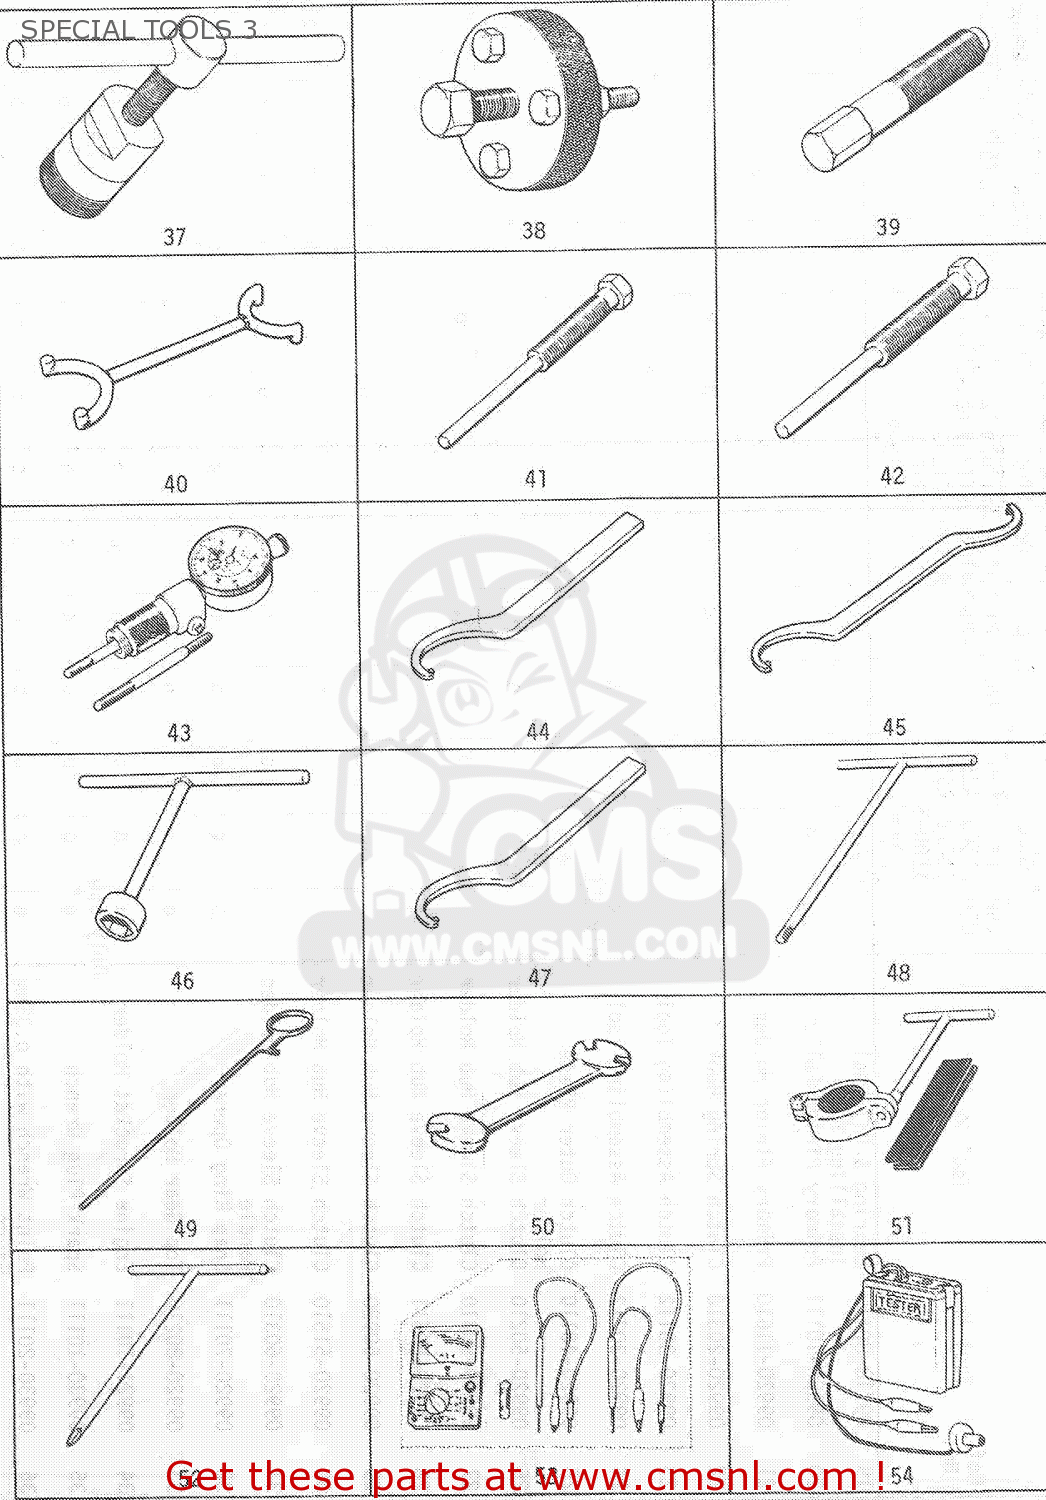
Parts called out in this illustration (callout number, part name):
38	ROTOR REMOVER
40	ROTOR HOLDER
43	TIMING GAUGE
45	STEERING STEM NUT WRENCH
47	STEERING STEM LOCK NUT WRENCH
48	FRONT FORK ASSE
49	FRONT FORK OIL
50	SPOKE NIPPLE WRENCH
51	FRONT FORK OUTER TUBE NUT WRENCH SET
52	T TYPE CROSS HEAD SCREW DRIVER (6MM)
53	UNIVERSEELMETER
54	TIMING TESTER
